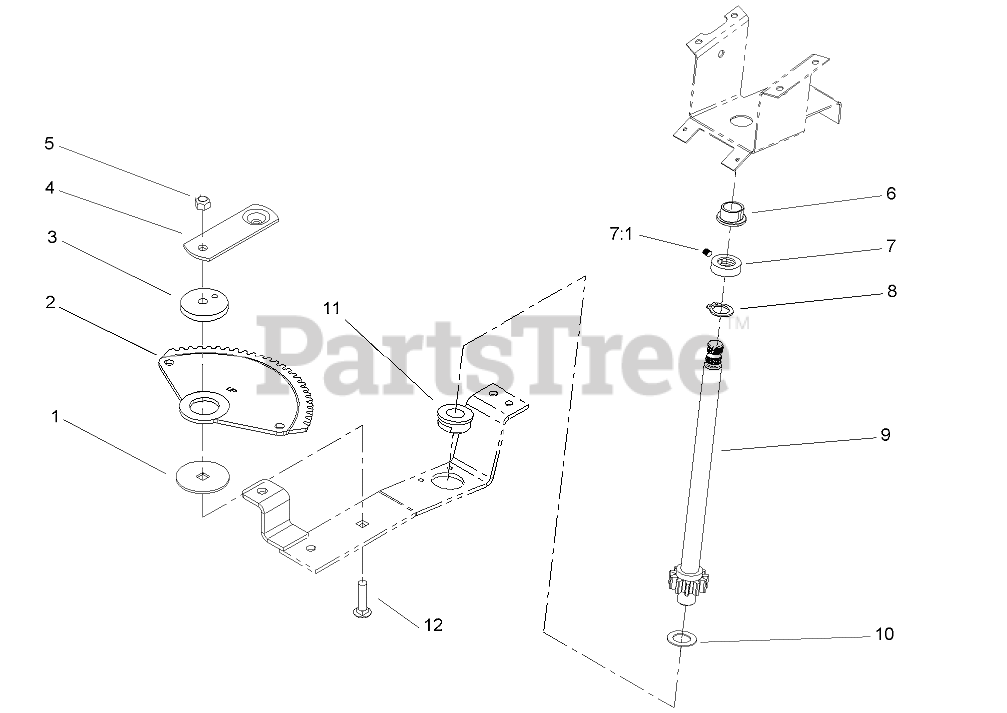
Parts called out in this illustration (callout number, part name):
1	WASHER-BEARING
2	SECTOR-GEAR
3	BUSHING
6	BEARING-FLANGED
7	COLLAR
7:1	SCREW-HSH
8	RING-RETAINING
9	SHAFT-STEERING, LOWER
10	WASHER
11	BEARING-WHEEL
12	SCREW-CARR
